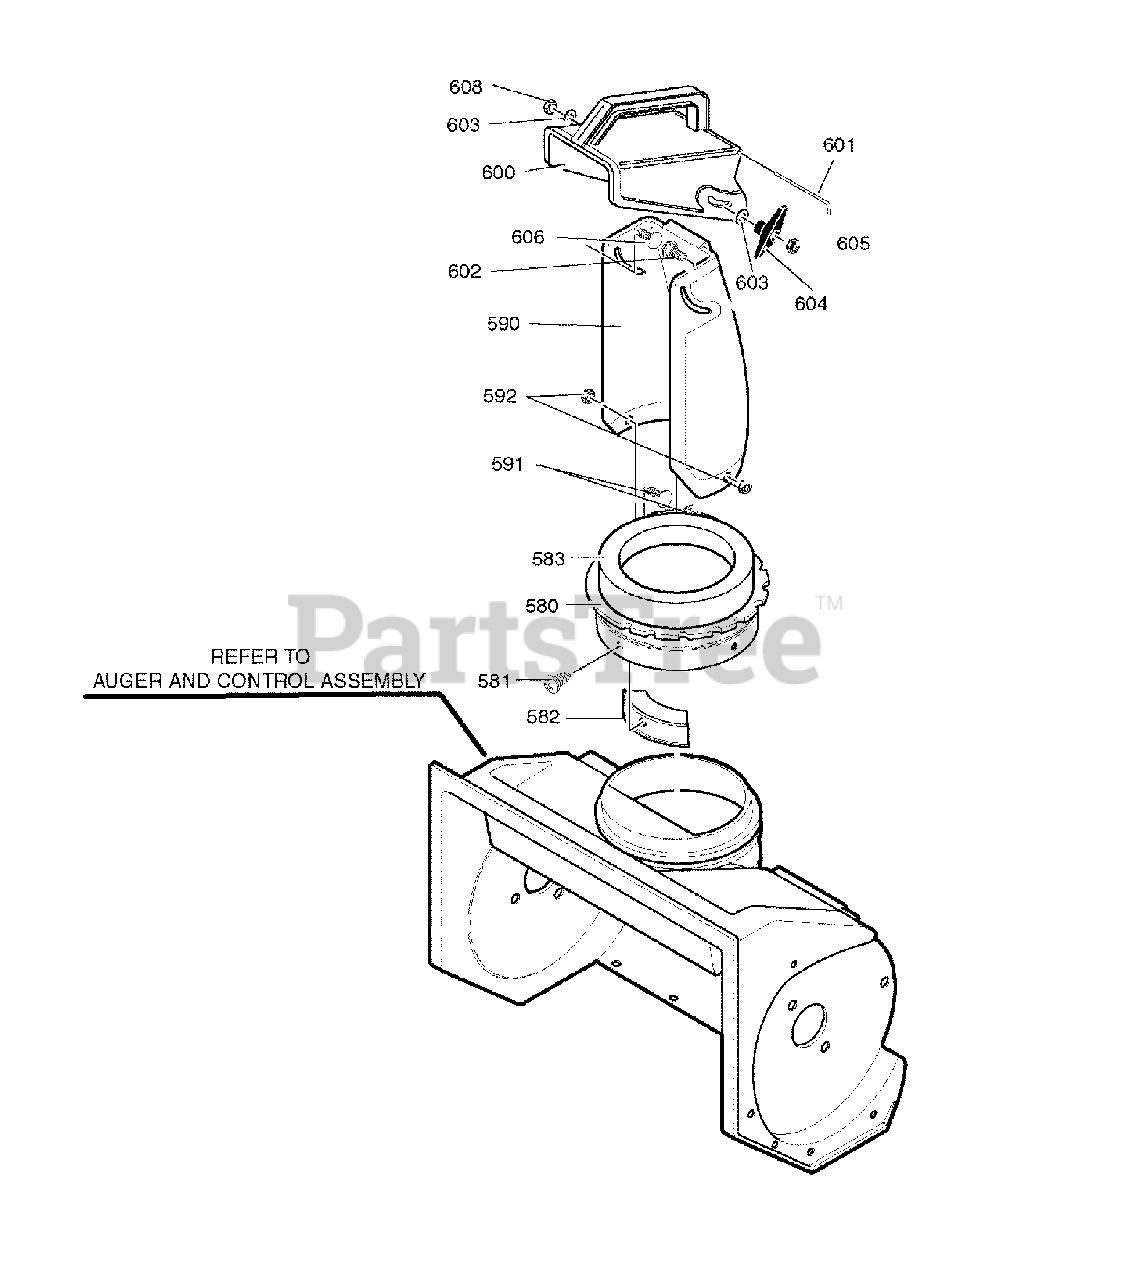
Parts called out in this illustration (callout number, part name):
580	CHUTE RING
581	SCREW, #10 X .50
582	GUIDE, CHUTE
583	DONUT, FOAM 21 PLAST A
590	CHUTE, DEFLECTOR LOWER
591	SCREW 1/4-20 X .75
592	NUT, 1/4-20, HEX CONTROL LOCK
600	CHUTE DELFECTOR, UPPER
601	WIRE FORM, HINGE 5.75
602	BOLT, 5/16-18 X 1.25 CARRIAGE
603	WASHER, FLAT .349 X .69 X .066
604	KNOB, WING
605	NUT, 5/16-18
606	SCREW, 5/16-18 X .75
608	NUT, 5/16-18, HEX CONTROL LOCK
